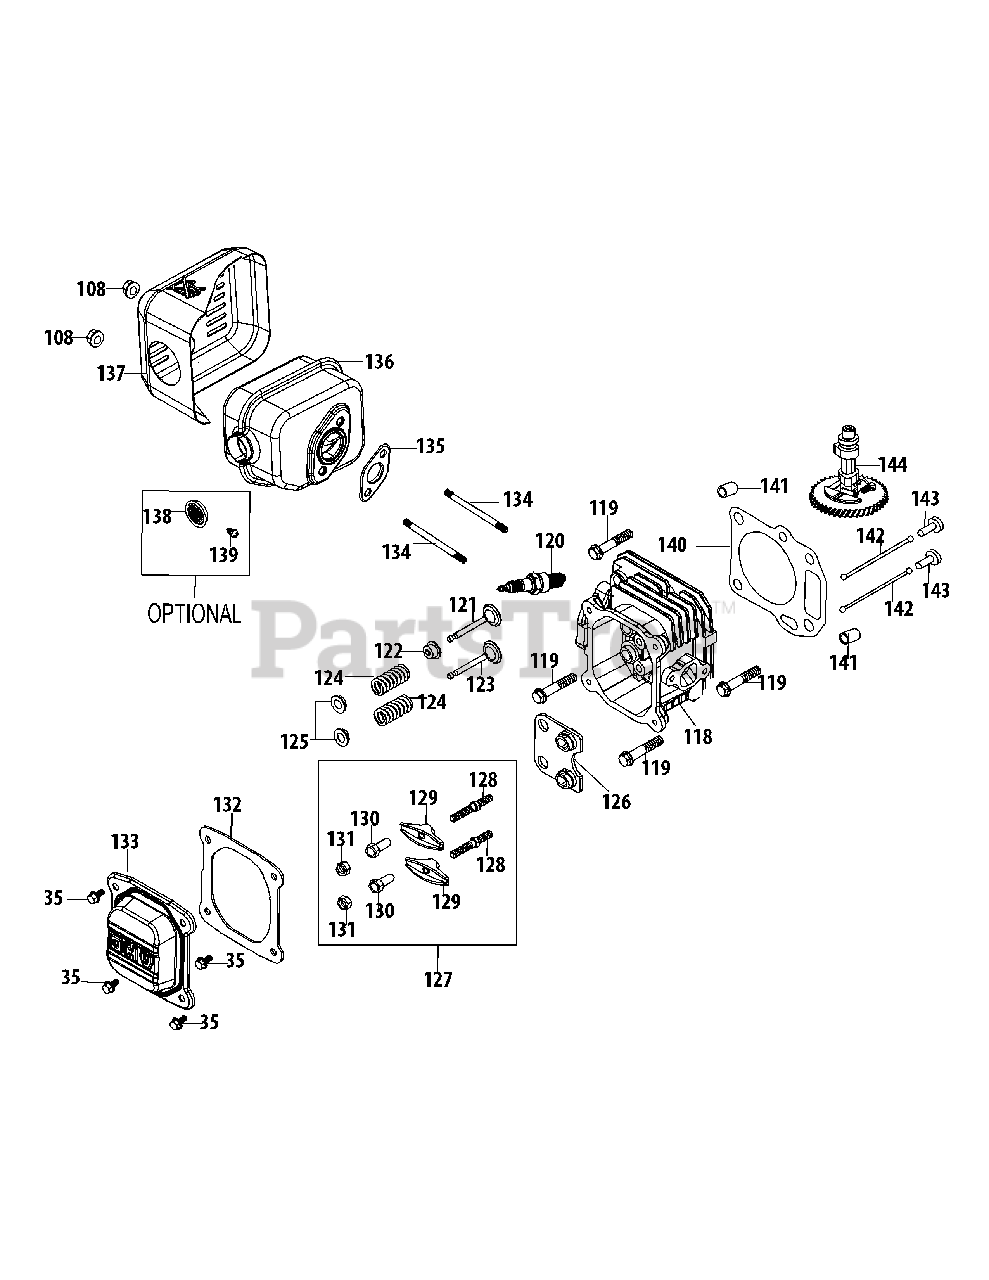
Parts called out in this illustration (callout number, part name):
35	BOLT M6-1 x 14 GR8.8
118	CYLINDER HEAD ASSEMBLY
118	CYLINDER HEAD
119	BOLT M8-1.25 x 54 GR9.8
120	SPARK PLUG
121	INTAKE VALVE
122	INTAKE VALVE SEAL
123	EXHAUST VALVE
124	VALVE SPRING
125	VALVE RETURN SPRING
126	PUSH ROD GUIDE
127	ROCKER ARM ASSEMBLY
128	PIVOT STUD
129	ROCKER ARM
130	VALVE ADJUST NUT
131	PIVOT LOCKING NUT
132	VALVE COVER GASKET
133	VALVE COVER
134	STUD M6-1 x 95
135	MUFFLER GASKET
137	MUFFLER SHIELD
138	SPARK ARRESTOR
139	SCREW M3.5 x 9.5
140	CYLINDER HEAD GASKET
142	PUSH ROD
143	TAPPET
144	CAMSHAFT ASSEMBLY
